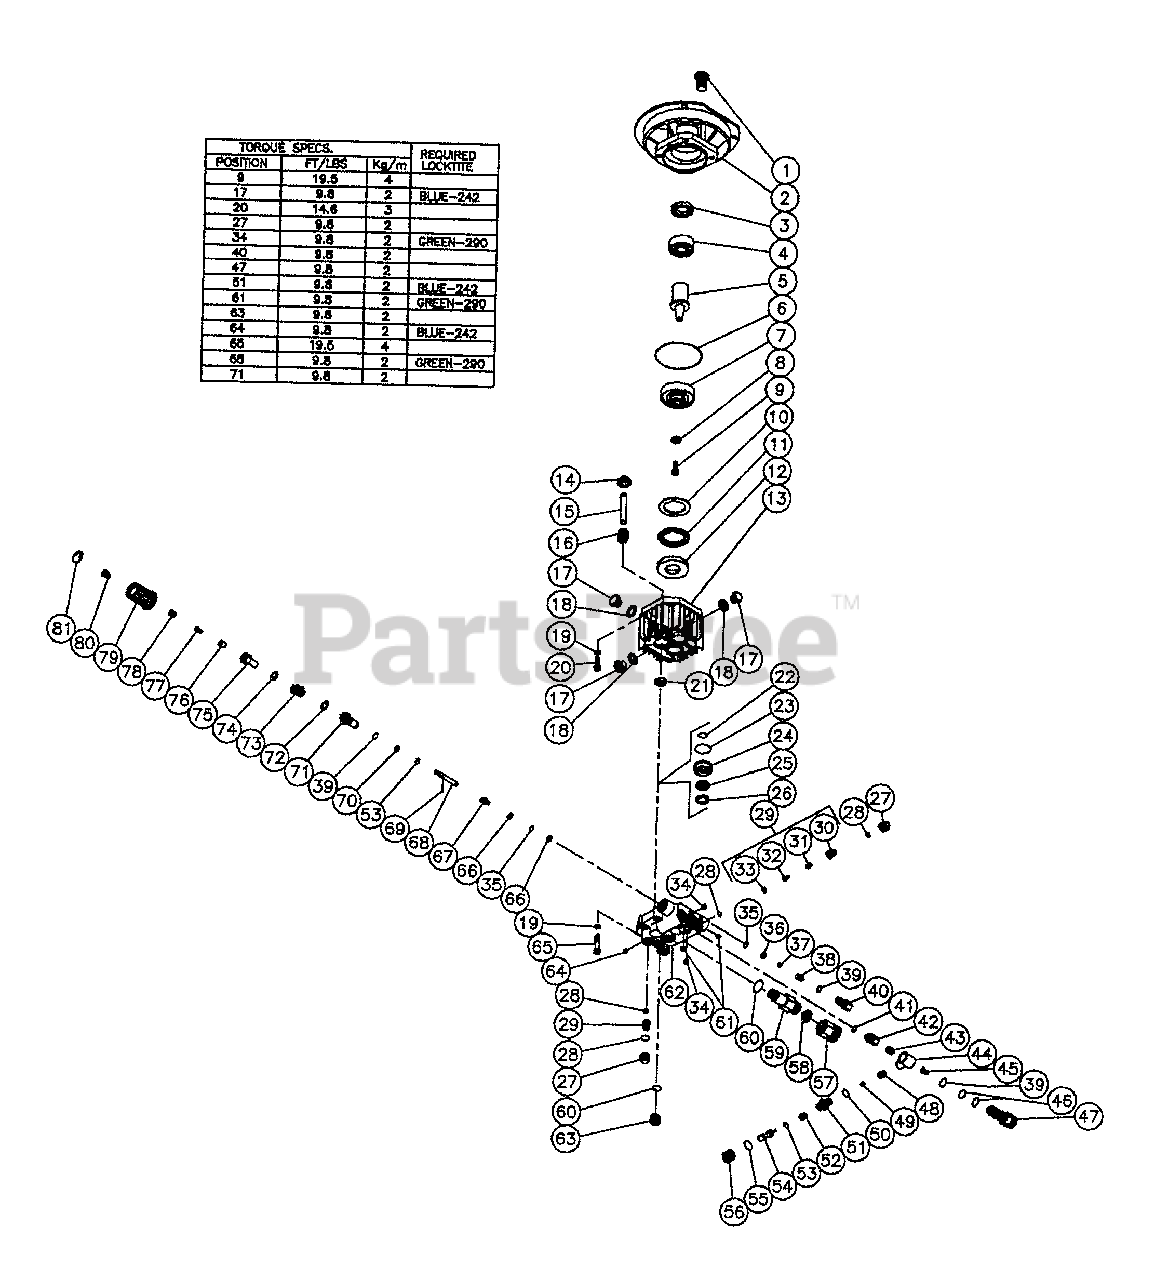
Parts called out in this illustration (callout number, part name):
3	Oil Seal
7	Wobble Plate
10	Bearing Disc
12	Bearing Disc
13	Pump Housing
14	Piston Spring Retainer
16	Piston Spring
17	Oil Drain Plug
19	Lockwasher
21	Oil Seal (See 07575-06)
22	O-ring (See 07575-16)
23	O-ring (See 07575-16)
24	V-Packing Retainer
25	V-Packing (See 07575-16)
26	Pack Ring (See 07575-16)
27	Valve Plug
29	Valve Complete (See 07575-17)
30	Valve Cage (See 07575-17)
31	Valve Spring (See 07575-17)
32	Valve Plate (See 07575-17)
33	Valve Seat (See 07575-17)
36	Valve Seat
38	Valve Spring
42	No Return Valve
44	Injector Body
45	Injector Nozzle
47	Pressure Outlet
48	Spring (See 07575-20)
49	Ball (See 07575-20)
50	O-ring (See 07575-20)
51	Injector Nipple
52	Injector Spring
53	O-ring (See 07575-20)
54	Injector Piston
55	Flexible Ring
56	Injector Regulation Knob
57	Garden Hose Connection
59	Inlet Connector
62	Manifold
63	Manifold Plug
66	Back-up Ring
67	Piston By-pass (See 07575-19)
68	Pressure Regulator (See 07575-19)
69	Roll Pin
70	Back-up Ring (See 07575-19)
71	Plug (See 07575-19)
73	Pressure Regulation Spring
75	Pressure Regulation Screw
76	Screw Support
78	Internal Screw
79	Pressure Regulation Knob
